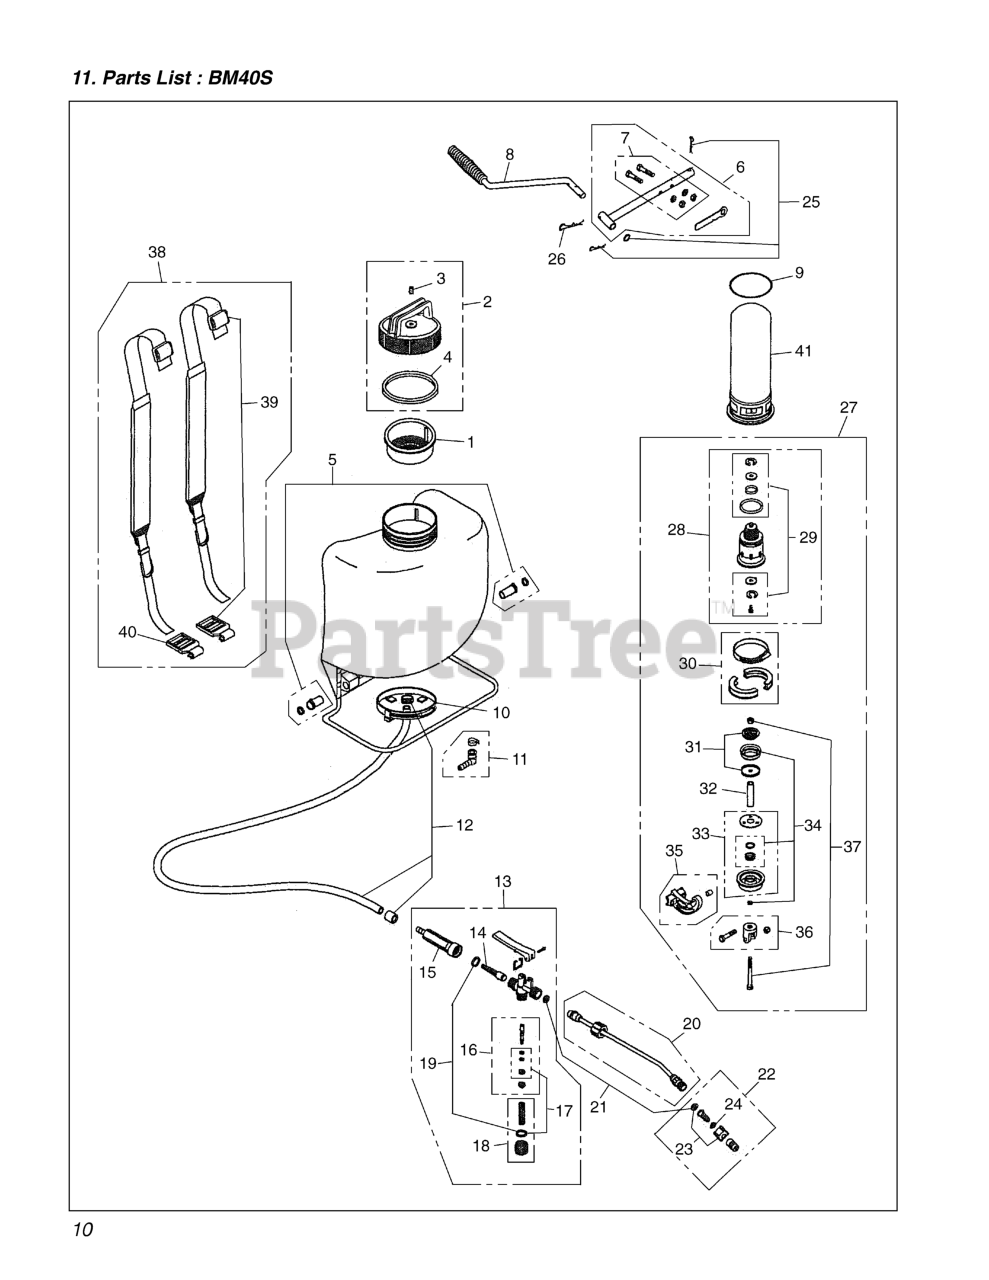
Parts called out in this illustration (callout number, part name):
1	TANK STRAINER
2	RED TANK LID (HANDLE, DUCK VALVE, SEAL)
3	DUCK VALVE
4	6
5	BEARINGS, NYLON
6	PUMP LEVER SET
7	SCREW & NUT SET
8	PUMP HANDLE (FOLD BACK TYPE)
9	O-RING, PRESSURE TANK
10	RETENTION CLAMP
11	90 DEGREE FITTING & CLAMP
12	HOSE & CLAMPS
13	SPRAY PISTOL W/FILTER & GRIP COMPL
14	FILTER (KIT 18F)
15	GRIP HANDLE (KIT 18F)
16	SPINDLE SET
17	O-RING SET, SPINDLE
18	PLUG SET
19	O-RING SET
20	20
21	WASHER SET, GUN & NOZZLE
22	SPRAY TIP SET
23	NOZZLE HOLDER
24	O-RING, SPRAY TIP
25	LOCKING PINS-PUMP HANDLE SM
26	LOCKING PIN-PUMP HANDLE LG
27	PUMP MODULE COMPL
28	CYLINDER FOR SEALED PISTON COMPL
29	O-RING & WASHER SET
30	1/2 MOON JAWS & CLAMPS
31	PISTON HOLDER & STAINLESS PLATE
32	SHAFT, HOLLOW BRASS
33	BASE & SEALS COMPL
34	PISTON & SEALS
35	CRANK & BRASS BUSHING
36	LEVER HOLDING SADDLE W/BOLT & NUT
37	BOLT & NUT PISTON HOLDER
38	SHOULDER STRAP
39	BELT HOOK & BUCKLE
40	HOOK, BELT
41	PRESSURE CHAMBER, SOLVENT RESISTENT
